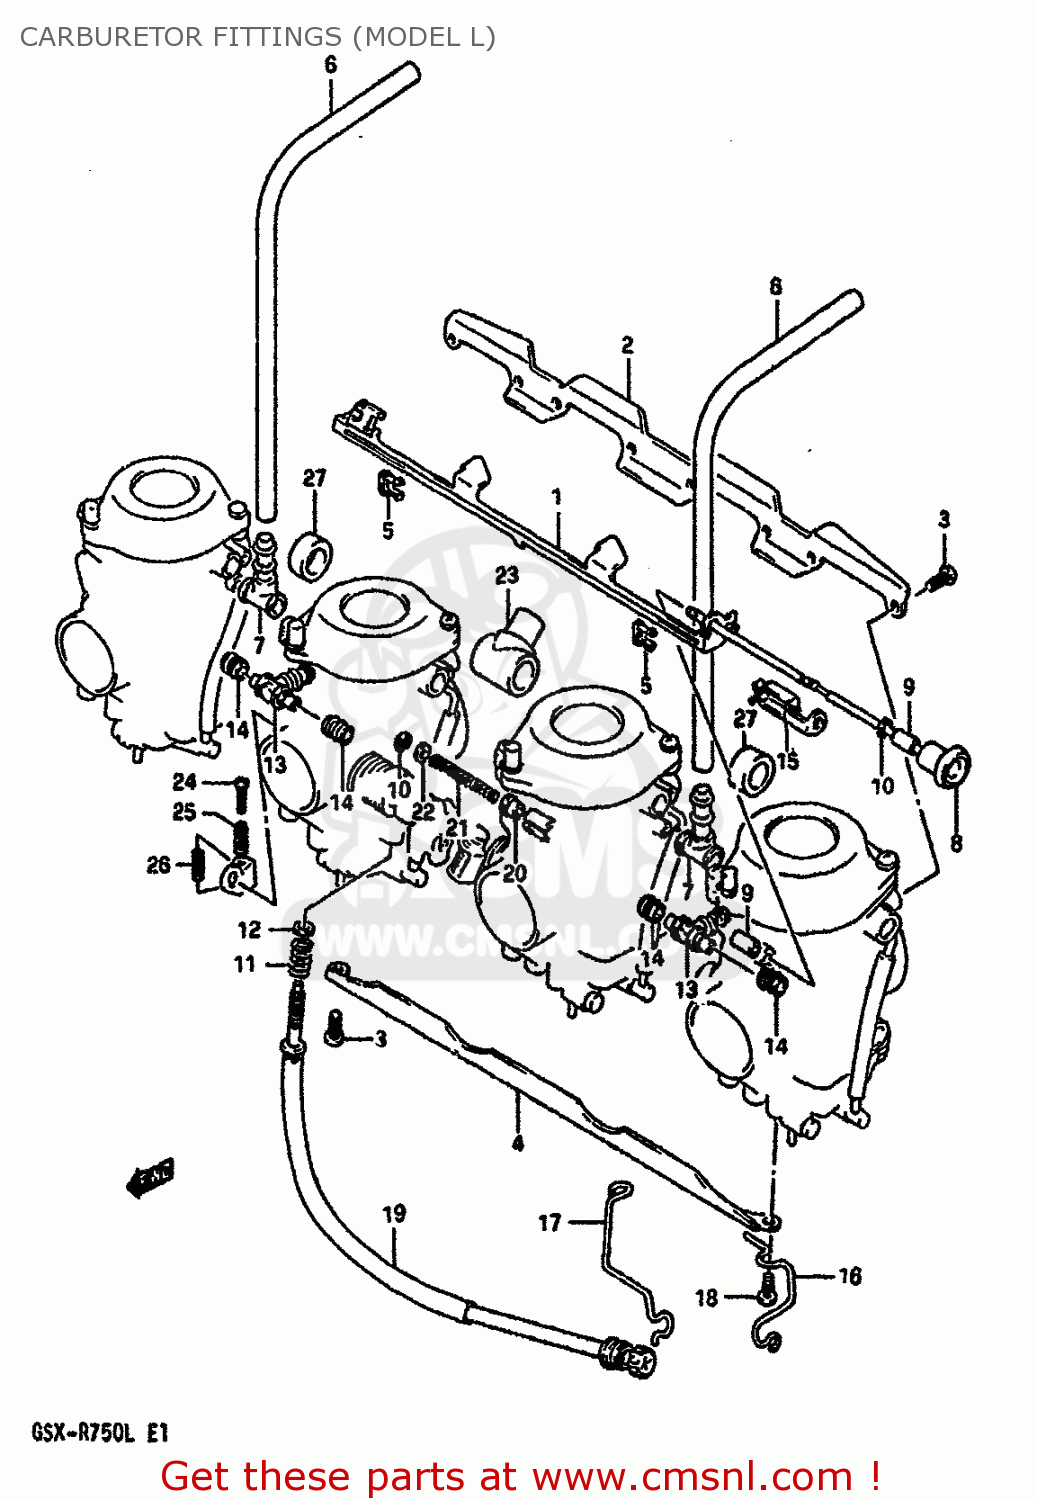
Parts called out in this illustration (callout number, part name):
1	LEVER
2	PLATE
3	SCREW
4	PLATE
5	HOLDER
6	HOSE
7	HOSE
8	SHAFT ASSY,STARTER
9	SPACER
10	E RING
11	SPRING
12	NUT
13	NIPPLE
14	SEAL
15	PLATE
16	CLIP
17	CLIP
18	SCREW
19	SPRING
20	RING
21	SEAL
22	WASHER
23	SCREW
24	SCREW
25	SPRING
26	SPRING
27	HOSE
28	O RING
29	JET,MAIN(117.5)
30	RING
31	VALVE ASSEMBLY,NEEDLE
32	PLUG
33	FLOAT ASSY
34	O RING
35	O-RING,NEEDLE VALVE
36	SCREW
37	SCREW
38	CAP
39	CLIP
40	PLUG
41	SHAFT ASSEMBLY
42	RING
43	COVER,DIAPHRAGM
44	CAP,STARTER
45	HOLDER,GUIDE
46	SPRING
47	PLUNGER ASSY
48	SCREW,PILOT
49	SPRING
50	WASHER
51	O RING,PILOT AIR SCREW
52	SCREW,GUIDE
53	O RING,DRAIN PLUG
54	JET,MAIN AIR (0)
55	JET,AIR(1.2)
56	RING
57	HOSE
58	CLIP
59	RING
